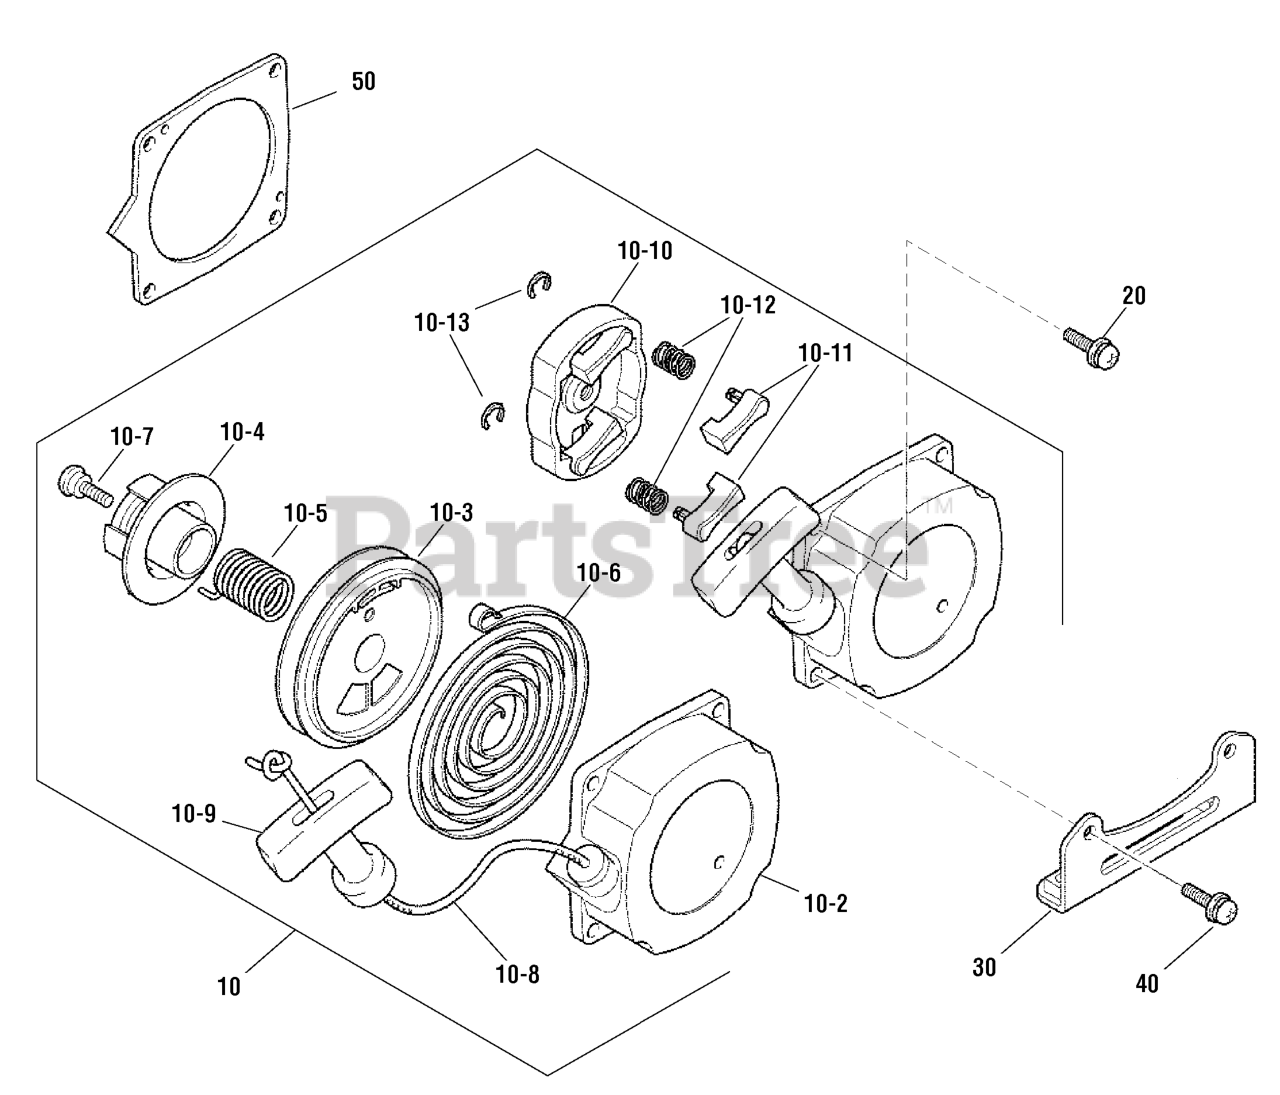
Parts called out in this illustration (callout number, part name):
10	RECOIL STARTER ASSEMBLY
10-2	CASE, Starter
10-3	REEL
10-4	CAM
10-5	SPRING
10-6	SPRING, Spiral
10-7	SCREW
10-8	ROPE, Starter
10-9	KNOB, Starter
10-10	PULLEY, Starter
10-11	RATCHET
10-12	SPRING, Return
10-13	SNAP RING
20	SCREW & WASHER
30	BRACKET, Tank
40	SCREW & WASHER
50	PLATE
